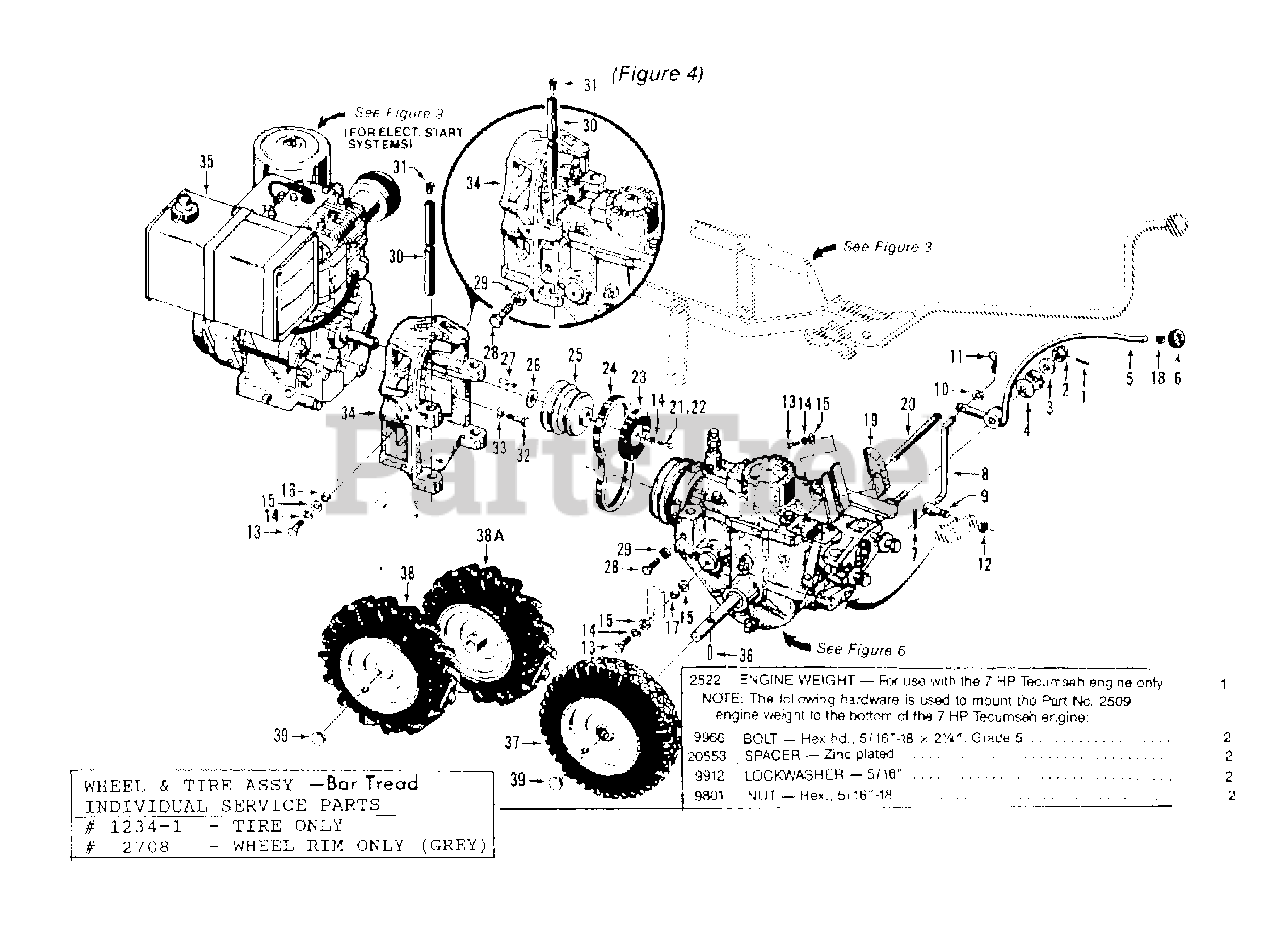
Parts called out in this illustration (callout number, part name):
1	PIN - spring, 1/8" dia., retains castle nut to threaded stud
2	NUT-castle (slotted), 1/2"-20.
3	WASHER- shoulder, 1/2" (shoulder faces disc washers)
4	WASHER- disc spring (concave surfaces face each other)
5	LEVER - wheel speed shift
6	KNOB - wheel speed shift lever
7	PIN - cotter, 3/32" x 1"
8	ROD - connecting rod, wheel speed shift lever
9	SWIVEL - connecting rod
10	WASHER - flat, 5/16",S.A.E.
11	PIN - hair cotter
12	LOCKNUT-hex. hd., 5/16"-18, retains swivel to eccentric lever
13	BOLT - hex. hd., 3/8"-16 x 1"
14	LOCKWASHER - springlock, 3/8"
15	WASHER - flat, 3/8", S.A.E. 9903
16	BUSHING - spacer, 21/64" (.325") long, yoke to engine mount
17	BUSHING - spacer, 19/64" (.300") long, yoke link to retaining plug
18	RING - retaining (tolerance ring)
19	BLOCK - belt adjustment, 3-7/8" long
20	ROD - belt adjustment, 7" long, with measuring gauge
21	BOLT - hex. hd., 3/8"-24 x 1-3/4", engine pulley
22	BOLT - hex. hd., 3/8"-24 x 1-1/2", engine pulley
23	DISC-reverse, rubber rimmed
24	BELT -forward drive
25	PULLEY- engine P.T.O. (Power Take Off)
26	SHIM - engine pulley, 1/16" thick
26	SHIM - same as above, 1/32" thick
27	KEY - engine pulley, 3/16" square x 2-1/2"
28	BOLT -hex. hd., 5/16"-18 x 1", Grades. Retains engine mounting bar
29	NUT -hex., 5/16"-18 (jam nut)
30	BAR- engine mounting
31	PLUG - thread protector, red plastic
32	BOLT- hex. hd., 5/16"-24 x 1-1/8", engine mounting
33	LOCKWASHER-springlock, 5/16"
34	MOUNT- engine to tiller
35	TECUMSEH ENGINE - 6 HP, recoil start,
35	TECUMSEH ENGINE - 6 HP, electric start,
35	7 HP TECUMSEH ENGINE-Recoil start
35	7 HP TECUMSEH ENGINE-Electric start
35	KOHLER ENGINE-8 HP Magnum, recoil start
35	KOHLER ENGINE - 8 HP Magnum, electric start
36	PIN -roll (spirol, 5/16" x 1-1/2" long, wheel hub to shaft
37	WHEEL & TIRE ASSEMBLY - standard tread, LEFT SIDE 4:00/4:80 x 8" tubeless tire with valve stem, mounted on single-piece steel wheel.
38	WHEEL & TIRE ASSEMBLY - bar tread, LEFT SIDE 4:80 x 8" tubeless tire with valve stem, mounted on single-piece steel wheel.
38A	WHEEL & TIRE ASSEMBLY - bar tread, RIGHT SIDE.
39	CAP - wheel hub
